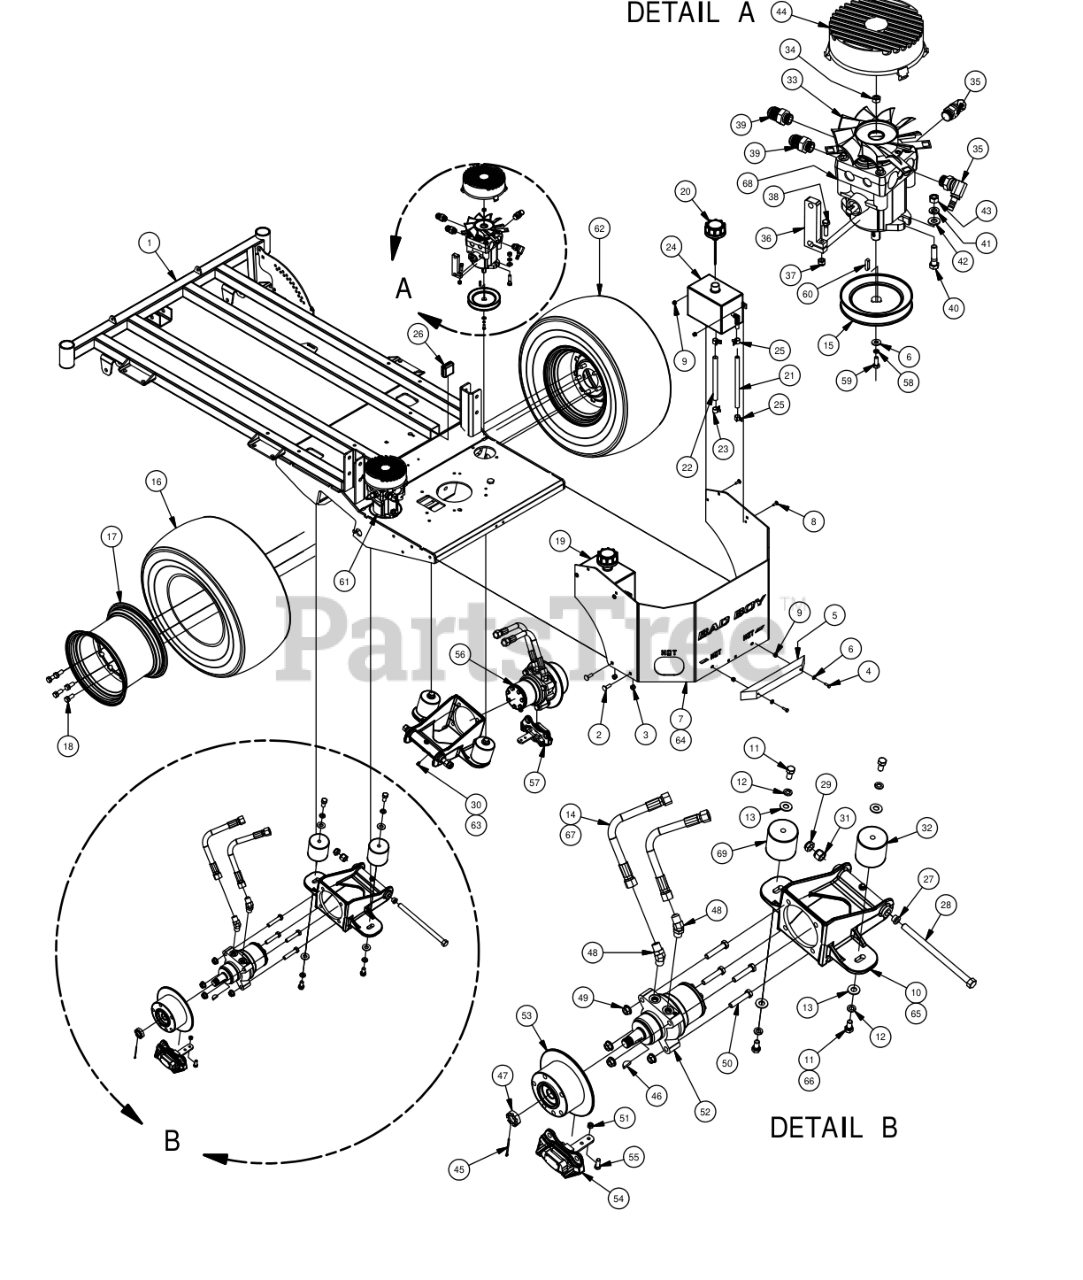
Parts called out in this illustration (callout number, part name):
1	2015 XP Frame
2	3/8" x 1 1/4" Carriage Bolt
3	3/8 Nylock Nut
4	1/4-20 x 1-1/4 GR 5 Hex Bolt
5	14" Rubber Bumper
6	1/4" Flat Washer
7	2015 Outlaw Rear Plate
8	1/4" x 3/4" Carriage Bolt
9	1/4-20 Nylon Insert flange Nut
10	60 Suspension kit Wheel Motor
11	1/2" x 1" Hex Bolt
12	1/2" Lock Washer
13	1/2" Washer (Grade 8)
14	18" hose Assembly W/forged 45 Degr
15	5" Pump Pulley
16	24 x 12-12 Tire Pro Maxxis
17	12x12" Black Wheel For 2015 Outlaw
19	Outlaw Hydraulic Tank Left
20	Hydraulic Tank Cap W/Dipstick
21	3/8" Clear Hose
22	1/2 Clear Braded Hose Priced/Foot
23	1/2 Hose Clamp
24	Outlaw Hydraulic Tank Right
25	3/8" Hose Clamp
26	2X2 Frame Plug
27	Flange Bushing for Deck Arm - Upper
28	5/8"x10" Hex Bolt (Grade8)
29	5/8" Nylock (1/2 Jam)
30	1/4" Drive in Grease Fitting (72" Suspension Kit Wheel Moter)
31	5/8 Std NC Nylock Nut
32	Vibration Mount-Green Dot
33	Hydraulic Fan
35	3/8" X 9/16"-18 ORB Male Fitting (S,A-2 P-4)
37	1/4" Nylock Nut
38	1/4-20 x 1 GR 5 hex bolt zinc
39	Hydraulic Pump Fitting 6400-10
40	3/8" x 1 1/2" Hex Bolt
41	3/8" Lock Washer
42	3/8" Flat Washer
43	3/8" Hex Nut
44	Fan Guard 6" Fits wheel Motor Pumps
45	1/8x2-1/4 cotter pin Zinc
46	Woodruff Key
48	45 Degree Fitting 31704-10-10
49	1/2" Flange Nut
50	1/2" x 2 1/2" Hex Bolt
51	5/16-18 Nylock Insert Locknut
52	15cc Parker Wheel Motor- Left
53	Brake Disk
54	XP/AOS Left Brake Caliper
55	3/8" x 1" Hex Bolt
56	15cc Parker Wheel Motor- Right
57	XP/AOS Right Brake Caliper
58	1/4" Lock Washer
59	M6-1.0 X 16MM Hex Bolt
60	5MM X 1 Square Key Stock
61	Left Pump 12cc
62	24 x 12 -12 Tire and Black Wheel Assembly
63	3/8" Threaded Grease Fitting (60" Suspension Kit Wheel Moter)
64	2016 Outlaw/XP Rear Cover (36 Vanguard Only)
65	72" Suspension Kit Wheel Moter
66	1/2-13 x 1 1/4 Hex Bolt (Only on 60" Suspension Kit Wheel Motor)
67	18" Hydraulic Hose Only
68	Right Pump 12cc
69	Vibration Mount-Blue Dot
